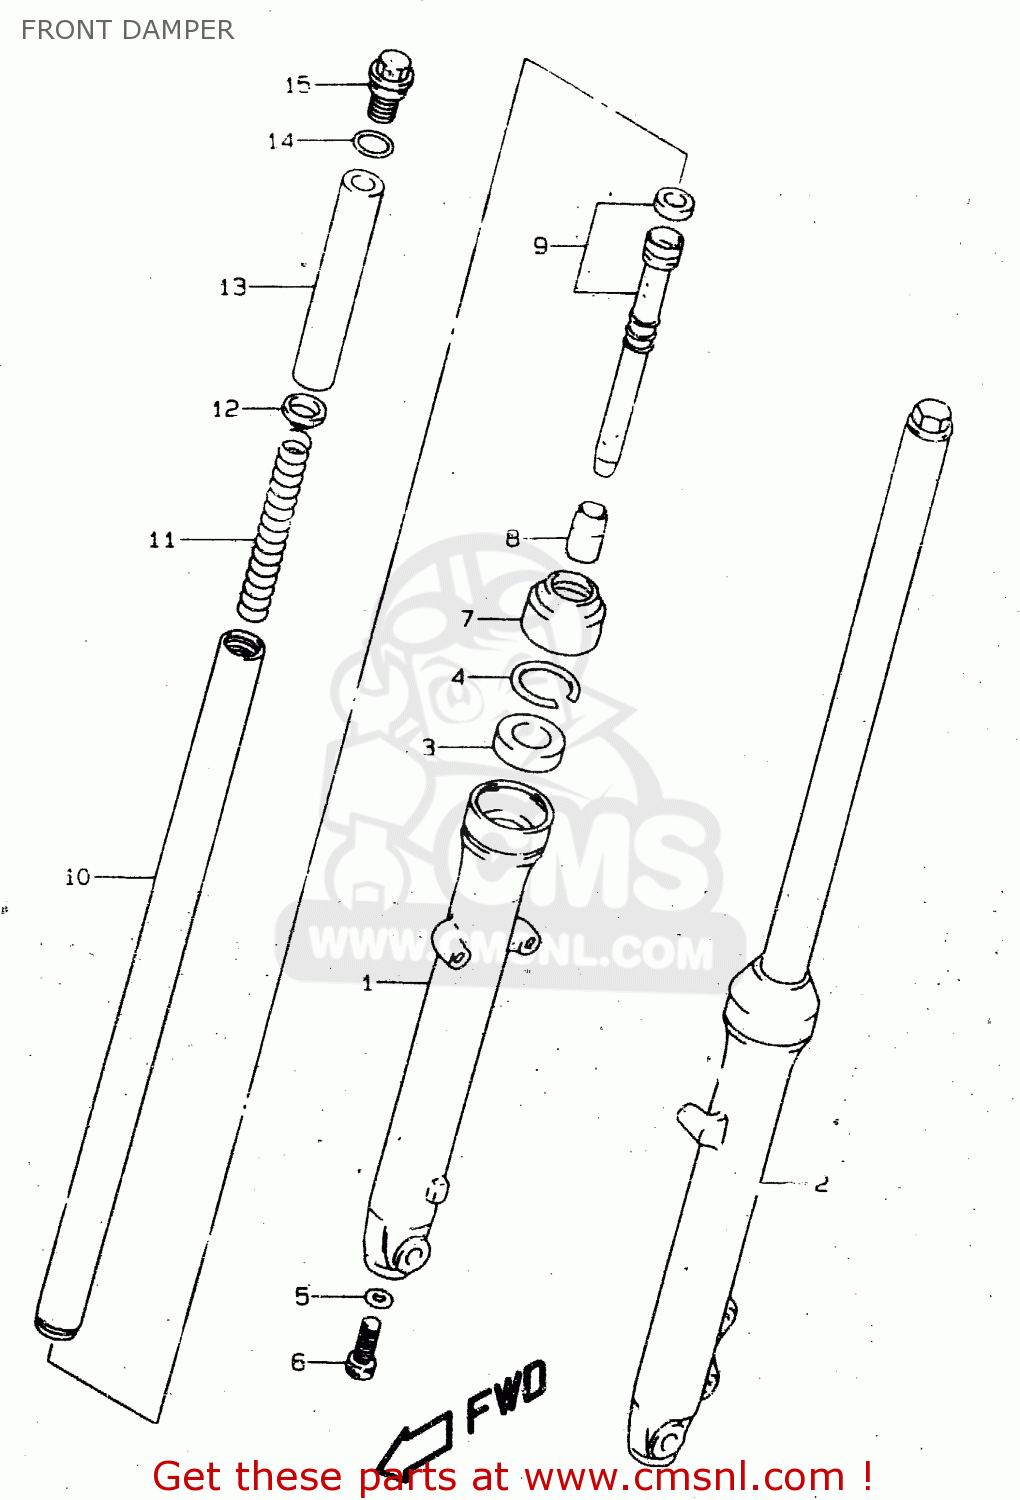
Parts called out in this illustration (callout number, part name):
1	TUBE,OUTER,R
2	TUBE,OUTER,L
3	SEAL,OIL
4	RING,SNAP
5	GASKET (NAS)
6	BOLT,FORK CYLINDER(10X25)
7	SEAL,DUST
8	PIECE,OIL LOCK
9	CYLINDER
10	TUBE,INNER
11	SPRING
12	GUIDE,SPRING COVER
13	SPACER
14	O RING
15	CAP
